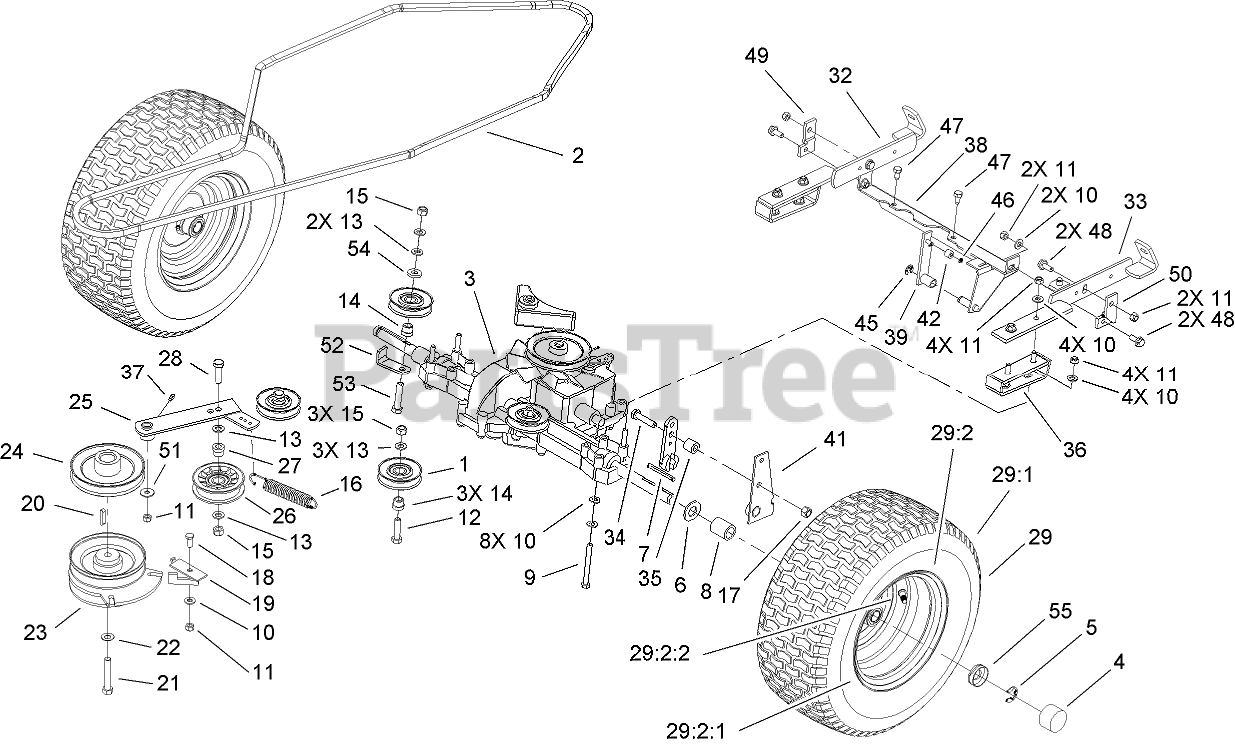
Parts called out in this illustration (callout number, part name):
1	PULLEY-IDLER
2	V-BELT-TRACTION
3	TRANSMISSION
4	CAP-HUB
5	CLIP-SPRING
6	WASHER
7	KEY-SQUARE
8	SPACER-AXLE
9	SCREW-HH
10	WASHER-PLAIN
11	NUT-LOCK, NI
12	SCREW-HH
13	WASHER-FLAT
14	BUSHING-IDLER
15	NUT-LOCK, NI
16	SPRING
17	NUT-LOCK, NI
18	SCREW-HH
19	RETAINER
20	KEY-SQUARE
21	SCREW-HH
22	WASHER-SPRING, BELLEVILLE
23	CLUTCH-ELECTRIC
24	PULLEY-ENGINE
25	ARM-IDLER
26	PULLEY-IDLER
27	BUSHING-IDLER
28	SCREW-HH
29	Wheel AND Tire ASM
29:1	TIRE
29:2	WHEEL ASM
29:2:1	Rim
29:2:2	Valve-Tire
32	Bracket-Right
33	Bracket-Left
34	SCREW-HH
35	SLEEVE
36	BRACKET-SUPPORT
37	FITTING-GREASE
38	Bar ASM
39	Arm-Switch
42	Roller
45	Stirrup
46	STIRRUP
47	SCREW-THREAD FORMING
48	SCREW-HEX
49	BRACKET-RIGHT
50	BRACKET-LEFT
51	WASHER-PLAIN
52	RETAINER-BELT
53	SCREW-HH
54	WASHER-FLAT
55	RETAINER-CAP, HUB
